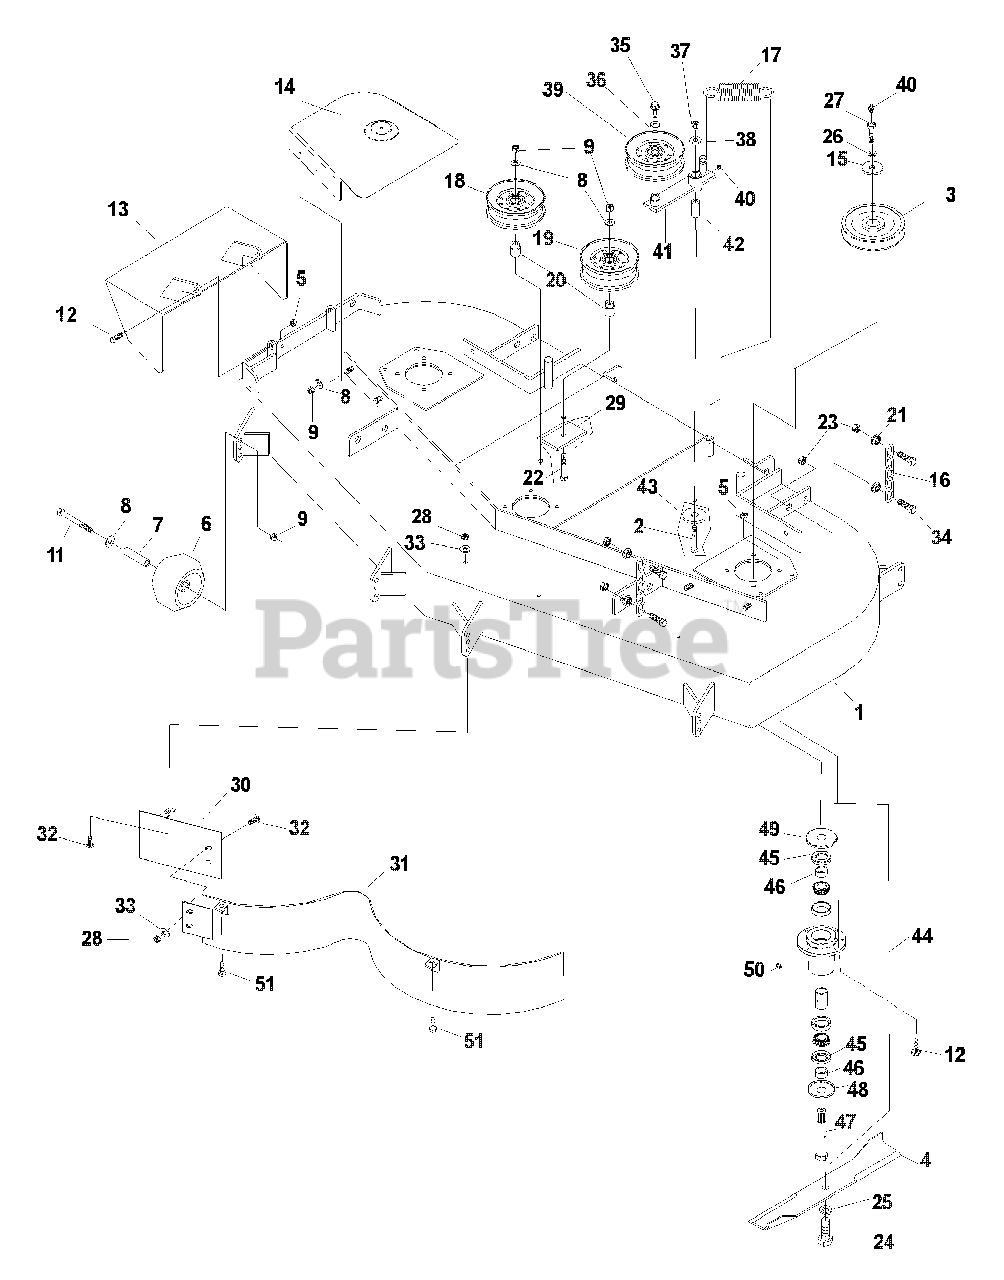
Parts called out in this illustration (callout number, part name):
1	DECK W/DECALS
2	HCS 1/2C X 3 1/4, GR. 5
3	PULLEY
4	BLADE, 18"
5	NUT 5/16C, NYLOC
8	WASHER 3/8, STD
9	NUT 3/8C, NYLOC
11	HSC 3/8C X 3 1/2
12	HCS 5/16C X 1 1/4
13	DISCRGE CHUTE
14	BELT SHEILD, RIGHT
15	HEAVY WASHER
16	LIFT CHAIN
18	IDLER PULLEY 1.31
19	IDLER PULLEY 1.62
20	IDLER BUSHINGS
21	NUT 7/16C, WHIZ
22	HCS 3/8C X 2 3/4
23	NUT, 7/16C, CENTERLOCK
24	HCS 5/8F X 1 1/4
26	LOCKWASHER, 7/16
27	HCS 7/16F X 1 1/2, SPEC
28	NUT 5/16C, CENTERLOCK
29	PAD
30	CENTER BAFFLE
31	MAIN BAFFLE
32	RHSNB 5/16C X 5/8
33	FLAT WASHER, 5/16
34	HCS 7/16C X 1 1/2
35	HCS 3/8C X 1 SER.
36	FLAT WASHER 3/8
37	NUT 1/2C, NYLOC
38	FLAT WASHER 1/2
39	IDLER PULLEY
40	ZERK
42	PIVOT BUSHING
43	SUPPORT WASHER
44	CUTTER HOUSING, COMPLETE
45	SHAFT SEAL
47	MINI SPINDLE
48	DUST CAP, BOTTOM
49	DUST CAP, TOP
50	GREASE POPET
51	HCS, 5/16C X 3/4
